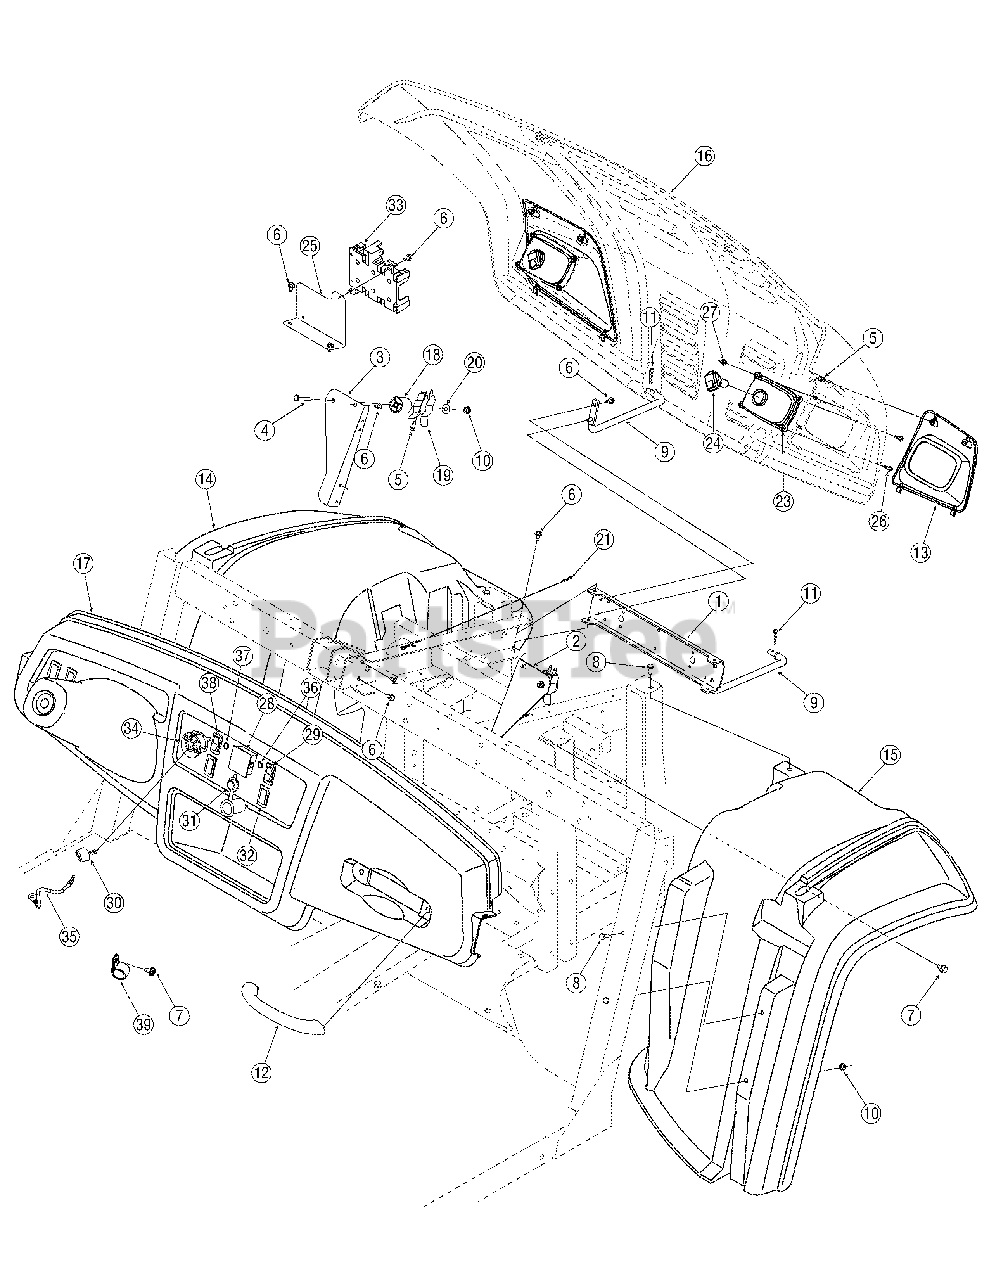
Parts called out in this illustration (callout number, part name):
4	Screw, 1/4-20, 1.75, Gr5, Std
5	Screw, #12-16 x .50
6	Screw, TT, 1/4-20 x .500
7	Screw, TT, 5/16-18 x .500
8	Screw, 1/4-20, .75, Gr5, Std
9	Rod, Mt, Hood
10	Nut, Flange Lock, 1/4-20
11	Pin, Cot, Int .08 X 1.42
12	Hndl, Bag, W/scr 400/500 S
13	Bzl, Hdlt RH
13	Bzl, Hdlt LH
14	Fdr, Lh 4x4
14	Fdr, Lh 4x4, Camo
15	Fdr, Rh 4x4
15	Fdr, Rh 4x4, Camo
16	Hood, 4x4, Camo
16	Hood, Green
17	Dash, Uv 4x4
18	Rlr, Latch, Hood
19	Spr, Latch, Hood
20	Wash, Fl, .283 X .75 X .030
23	Headlight Assembly (Incl. # 24)
24	Headlamp Bulb
26	Screw, TT, #10-24 x .750
27	Nut, Hex Lock, #10-24
28	Meter, Ind., Hour Flat Face
29	Switch, 4x4, Rocker
30	Key, Delta, Plastic
31	Recptl, Pwr, 12v
32	Pnl, Plug, Switch
33	Relay, Hldr, 3-Way
34	Switch, Key, 4 Pos. Delta
35	Engine Ground Wire
36	Lgt., Ind., Red, LED
37	Lgt., Ind., Yellow, LED
38	Switch, Headlight, Rocker
